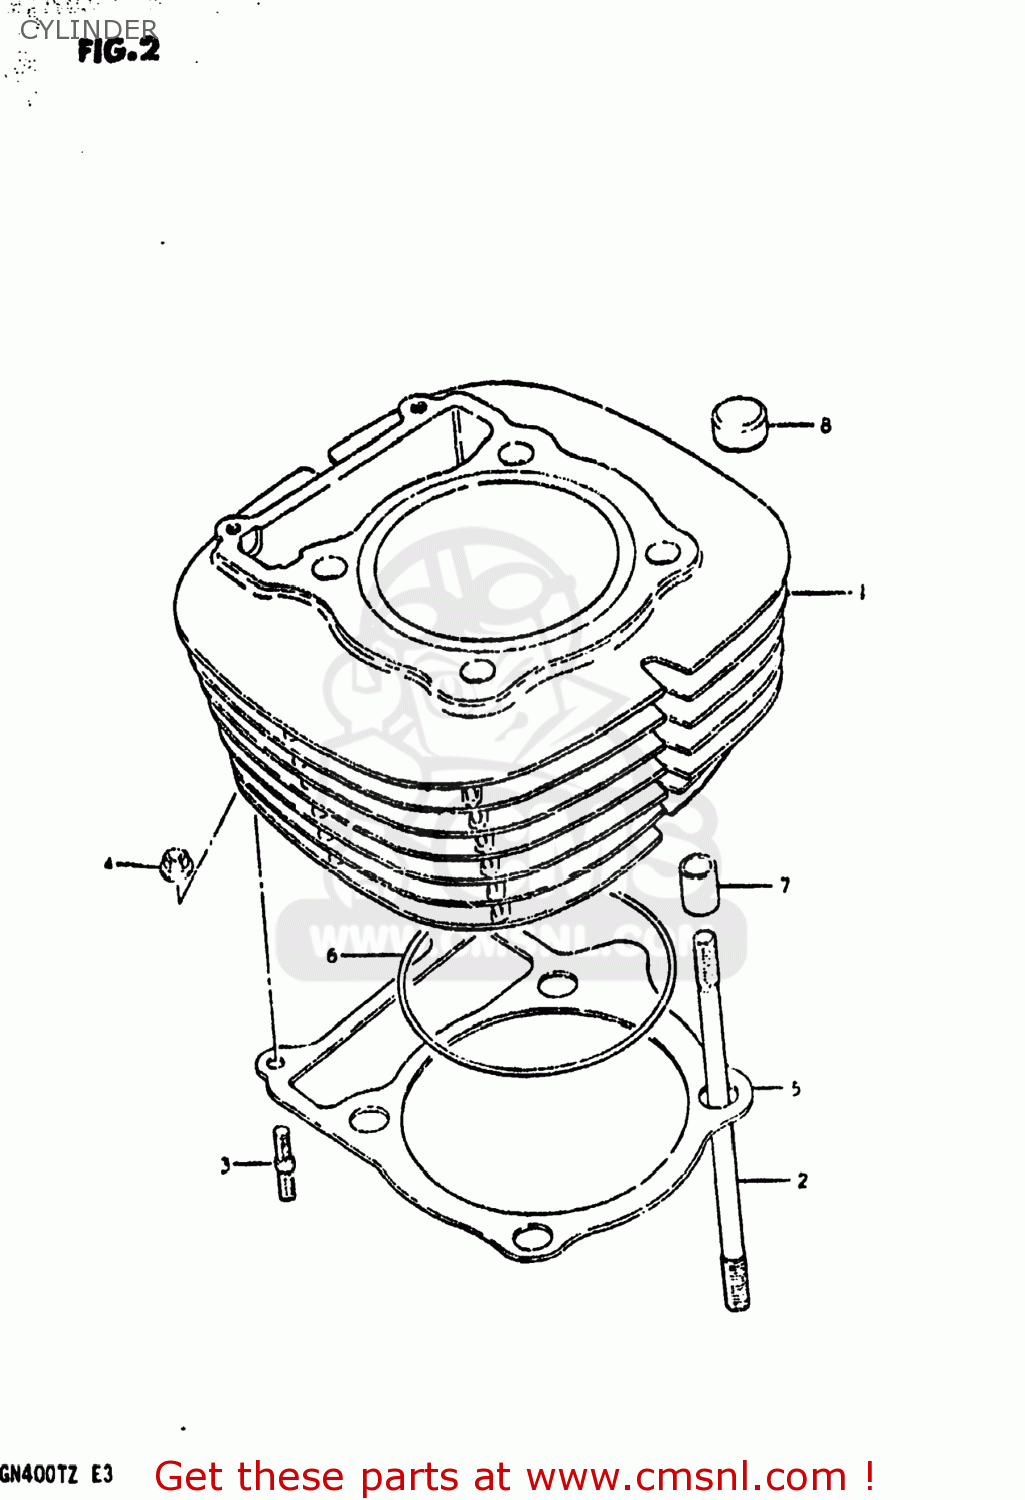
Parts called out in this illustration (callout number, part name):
1	CYLINDER
2	STUD
3	STUD 6X20
4	NUT
5	GASKET,CYLINDER (MCA)
6	O RING(D:2,ID:87)
7	PIN
8	PAD,CYLINDER HEAD
